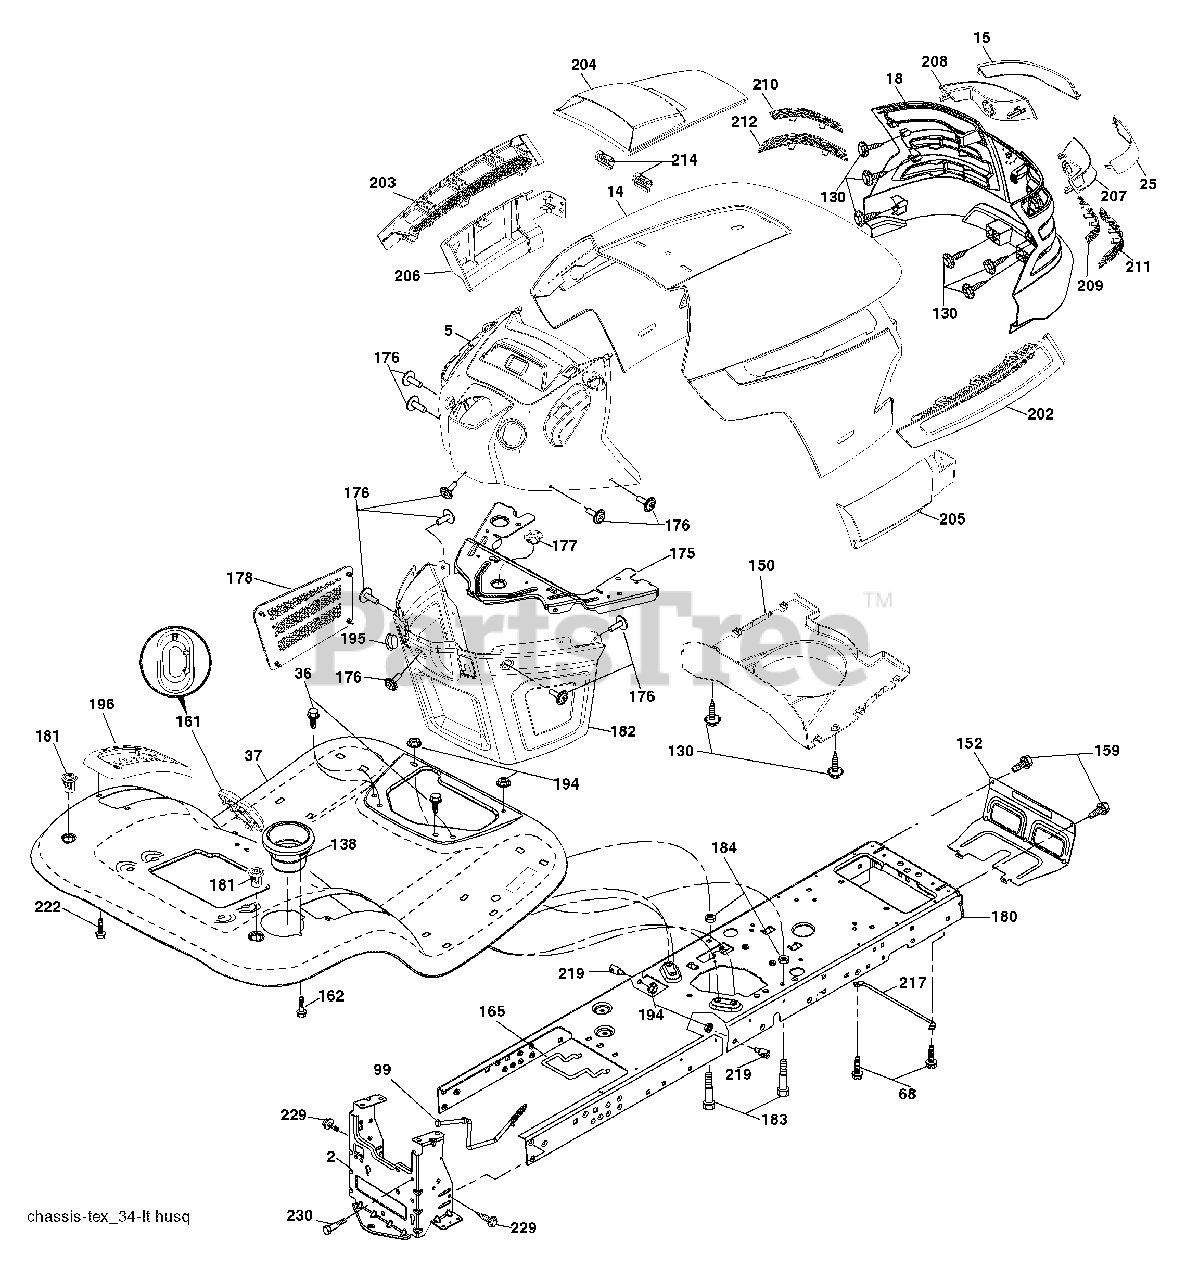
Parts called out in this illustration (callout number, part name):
5	Dash
14	Hood
18	Grille/Lens Asm.
36	Screw 5/16-18 x 3/4
37	Fender
68	Screw Thdrol 5/16-18 x 1/2
99	Rod Asm Bypass
130	Screw 10 x 3/4 Single Lead-Hex
138	Cupholder
152	Shield Browning
159	Screw 3/8-16 x 3/4
161	Window Fuel
165	Support Tank Rear
175	Crossmember
176	Screw 10-24 x 5/8
177	Bushing Steering
178	Cargo Net Asm.
180	Chassis
181	Bushing Mtg. Fender Crgo
182	Dash Lower
183	Bolt Fin Hex 5/16-18 unc x 1-1/4
184	Spacer Fender
194	Nut Lock Hex Flange 5/16-18
195	Plug Hole Dash Lower
196	Console Asm. Deck Lift
202	Vent Side Hood RH
203	Vent Side Hood LH
204	Vent Top Hood
205	Skirt Hood Side RH
206	Skirt Hood Side LH
209	Insert Hex Top RH
210	Insert Hex Top Lh
211	Insert Hex Bottom RH
212	Insert Hex Bottom LH
214	Clip Retainer Tinner
217	Rod Pivot
219	Stud Fastner
222	Screw Thdrol 1/4-20 x 5/8
229	Screw Hexwsh Thdr 3/8-16 x 3/4
230	Bolt Shoulder 5/16-18
